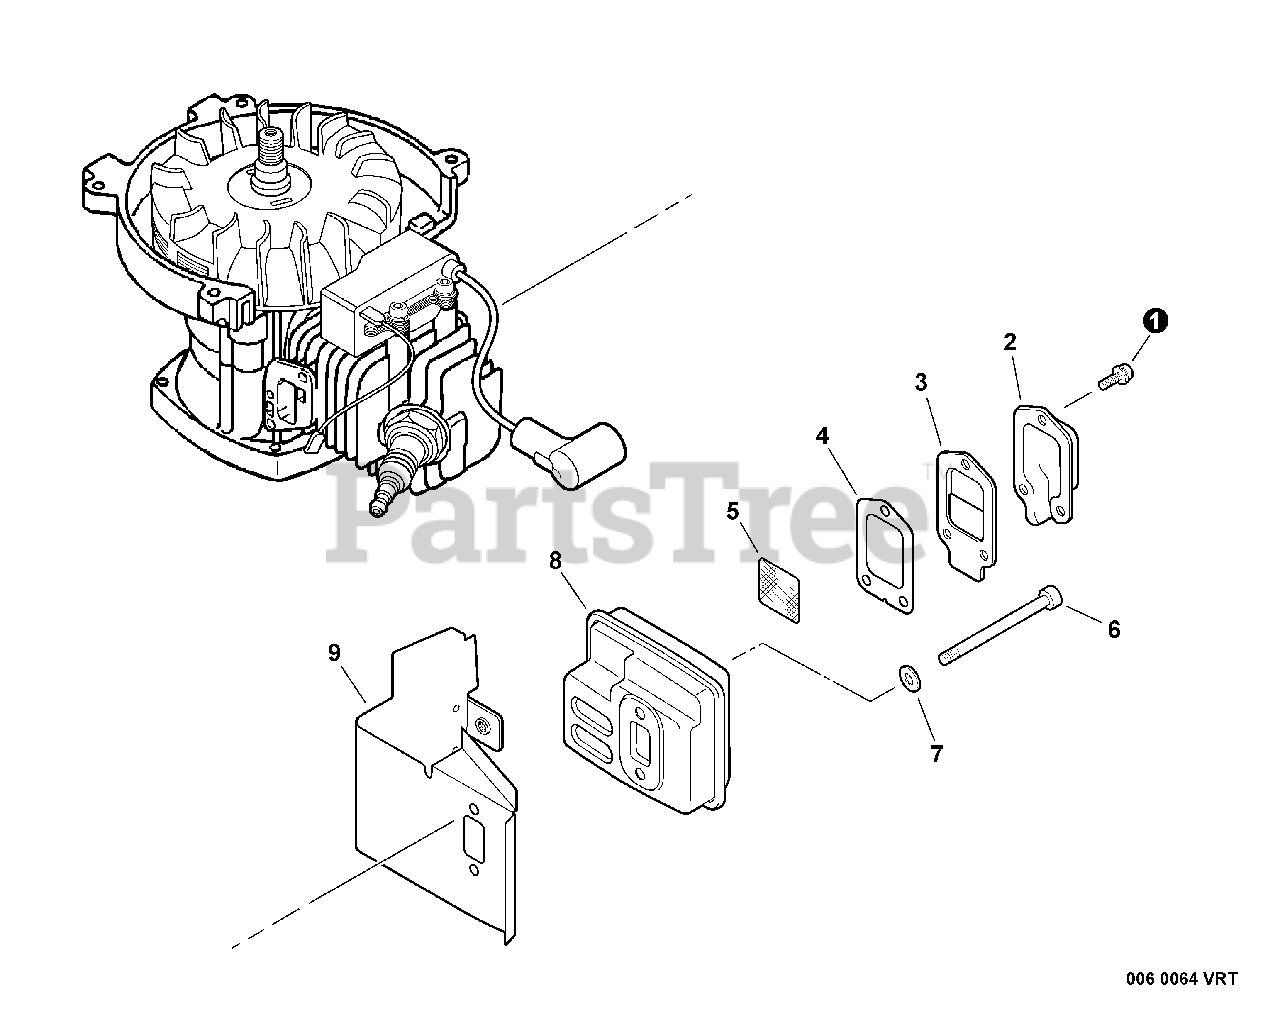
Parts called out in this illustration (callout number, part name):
1	SCREW - 4X10
2	GUIDE, EXHAUST - OUTER
3	GASKET, EXHAUST - INNER
4	GASKET, EXHAUST
5	SCREEN, SPARK ARRESTOR
6	SCREW - 5X50
7	WASHER - 5
9	SHIELD, EXHAUST
